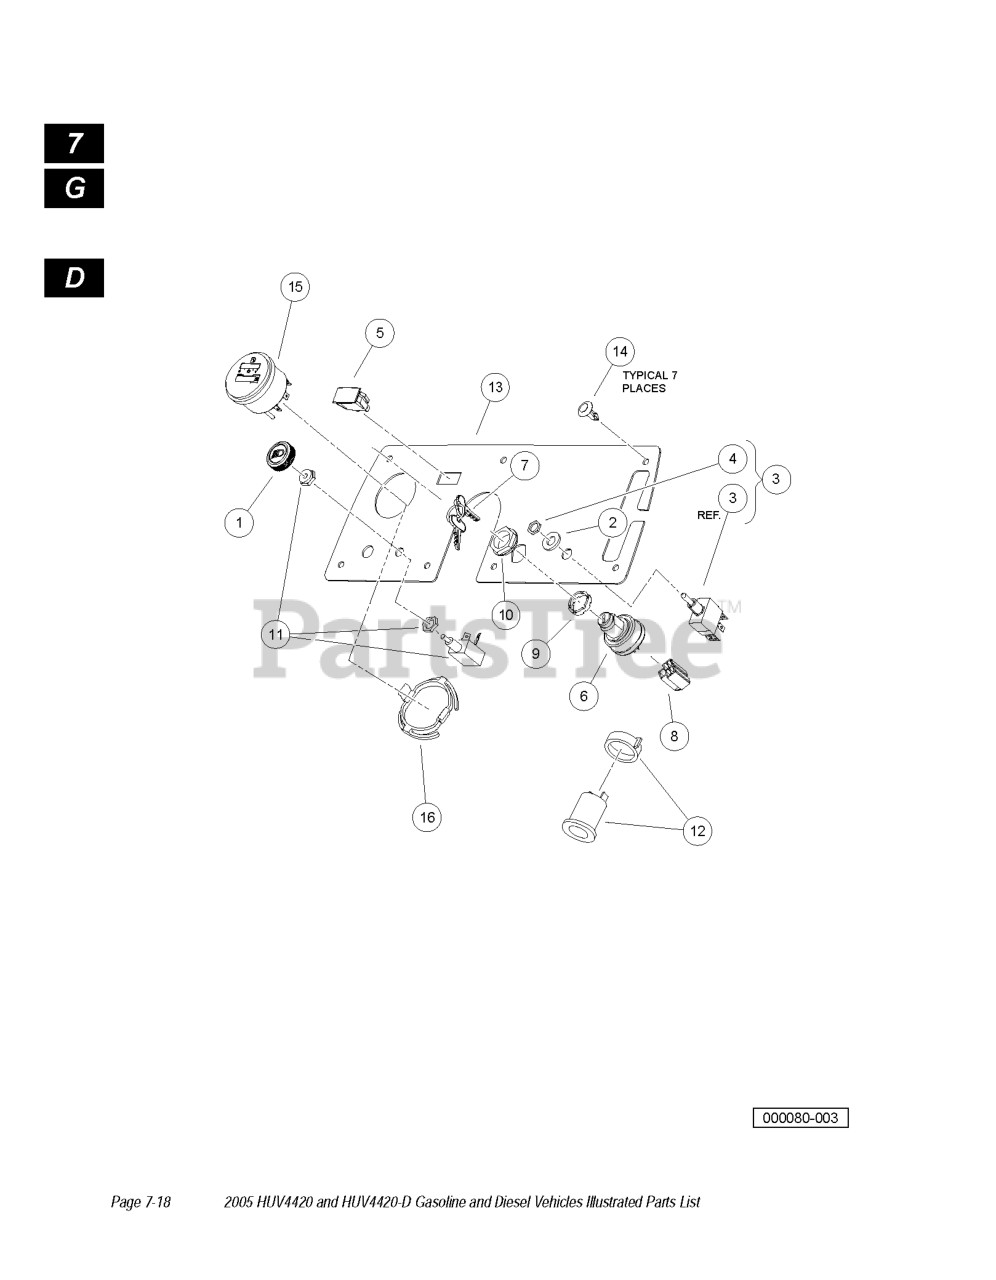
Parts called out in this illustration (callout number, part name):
1	LIGHT SWITCH KNOB
2	WASHER, 7/16 FLAT
3	TOGGLE SWITCH
5	LIGHT, OIL
6	KEY SWITCH 12V KEY START
9	SPACER, KEYSWITCH
10	NUT, KEYSWITCH
11	SWITCH, LIGHT
12	ACCESSORY RECEPTACLE
13	PANEL, INSTRUMENT, GAS
14	SCREW, TUFLOK PANEL, 1/4
15	GAUGE FUEL-HOUR SEP GND
16	CLIP METER ROUND
